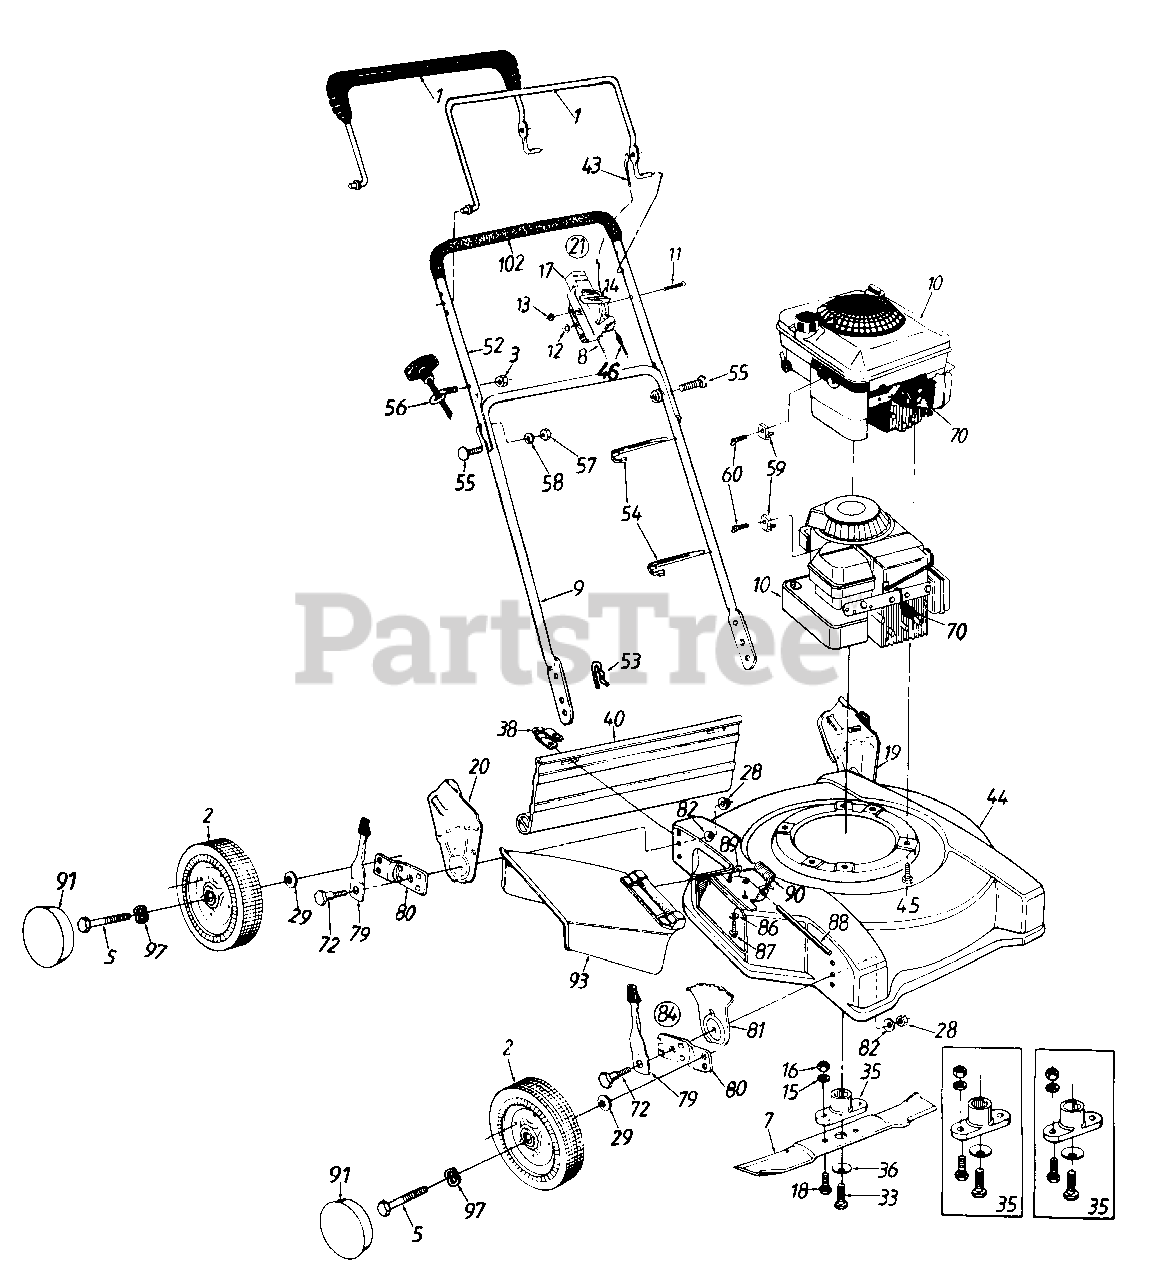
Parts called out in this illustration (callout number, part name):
2	Wheel Ass'y. Comp. Diamond Tread (7")
3	Hex L-Nut 1/4-20 Thd.
5	Axle Bolt
7	20" Blade
8	Throttle Control Wire - 51"
9	Lower Handle
10	Engine
11	Oval C-Sunk Mach. Scr.
12	Spr. Wash..66" I.D.
13	Hex L-Nut 1/4-20 Thd.
14	Throttle Lever
15	L-Wash. 3/8" I.D.
16	Hex Nut 3/8-24 Thd.
17	Throttle Body
18	Hex Bolt 3/8-24 x 1.0" Lg.
19	Wheel Brkt. Ass'y.- L.H.
20	Wheel Brkt. Ass'y.- R.H.
21	Throttle Box Comp.
28	Hex Nut 3/8-16 Thd.
29	Bell-Wash..40" I.D. x .88"
33	Hex Bolt 3/8-24 x 1.5" Lg.
35	Blade Adapter Kit
36	Bell-Wash..39" I.D.
38	Hinge Clip
40	Rear Flap Ass'y.
44	20" Deck Ass'y.
45	Hex Wash. Hd. TT-Tap Scr. 3/8-16 x 1.00" Lg.
46	Control Cable - 39"
54	Cable Tie
55	Curved Carriage Bolt 5/16-18 x 1.38" Lg.
56	Rope Guide
57	Hex Nut 5/16-18 Thd.
58	L-Wash. 5/16" I.D.
59	Cable Clamp
60	Hex Wash. Hd. Scr. #10-32 x .62" Lg.
70	Spark Plug Boot
72	Shoulder Bolt .50" Dia.
79	Spring Lever Ass'y. w/Knob
81	Height Adj. Plate
82	Bell-Wash..39" I.D. x 1.38"
84	Front Height Adj. Ass'y. Comp.- R.H.
86	Bell-Wash..285" I.D. x .75" D.D.
87	Hex Wash. Hd. Tap Scr. 1/4-20 x .5" Lg.
88	Hinge Pin
89	Adapter Plate
90	Torsion Spring
91	Hub Cap Gray (5-1/2 Dia.)
93	Chute Deflector Ass'y. Comp.
97	Wave Washer .53" I.D.
102	Foam Grip
